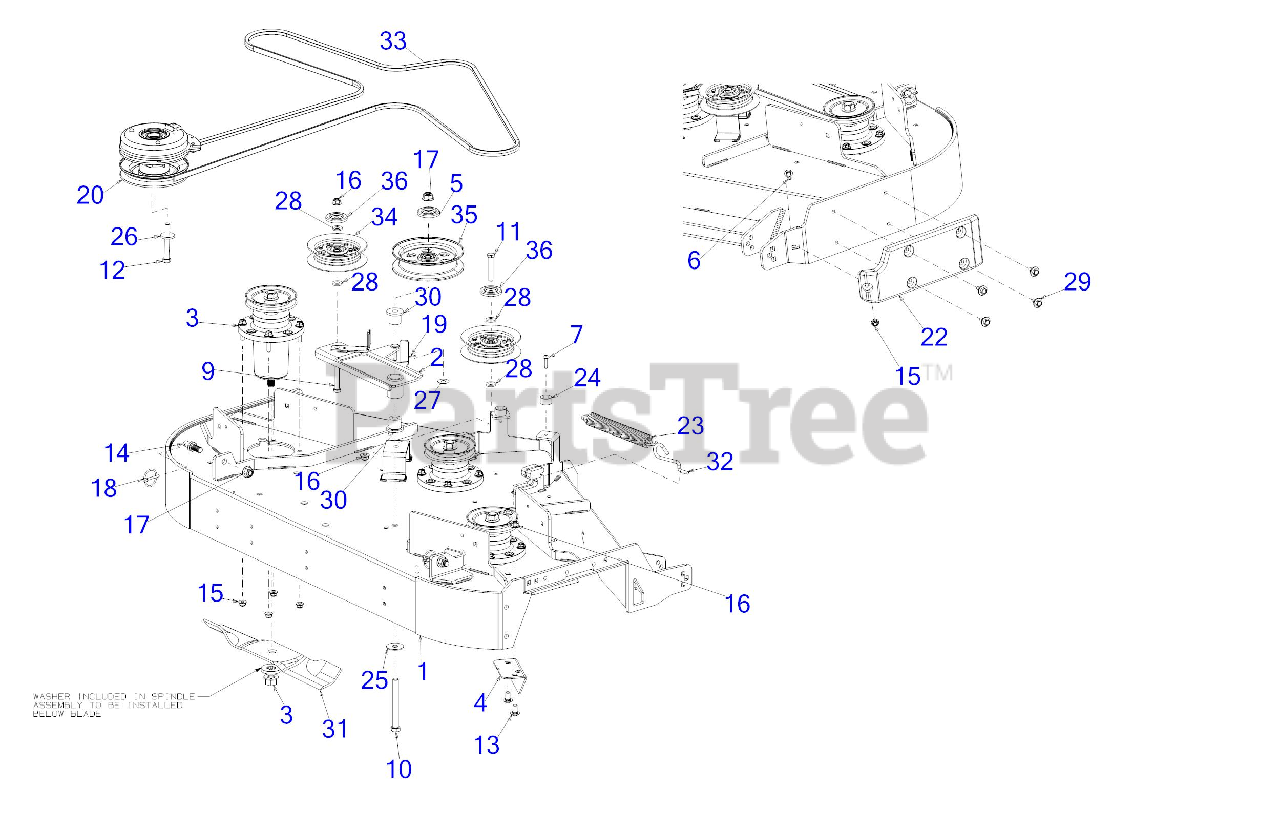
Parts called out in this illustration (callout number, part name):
2	IDLER ARM ASSEMBLY
3	SPINDLE ASSEMBLY
3	Cub Cadet 48" SPINDLE ASSEMBLY (07417)
5	PULLEY CAP
6	CARRIAGE BOLT 5/16-18 x 1.00
7	SCREW 1/4-20 x 1.0
9	HEX SCREW-3/8-16X2.5 GR5
10	SCREW 1/2-13 x 4.5 GR 5
11	SCREW 3/8-16 x 2.25 GR5
12	SCREW 7/16-20 x 3.25 GR5
13	CARRIAGE BOLT 3/8-16 x .75
15	FLANGE LOCK NUT 5/16-18
19	COTTER PIN 3/32
20	ELECTRIC PTO CLUTCH
22	DECK SKID PLATE (LH)
23	EXTENSION SPRING
25	WASHER .51 x 1.5 x .07
26	FLAT WASHER .445 x 1.248 x .170
27	FLAT WASHER
28	FLAT WASHER
29	SHOULDER SCREW .43X.29X5/16-18 TT
30	SHOULDER SPACER
31	17" BLADE (HI LIFT)
31	Cub Cadet 48" HI LIFT BLADE SET
31	17" HI-LIFT BLADE 0.756 ID
31	LOW-LIFT 17" BLADE (48"DECK)
31	BLADE-HI LIFT 17.0
31	17" BLADE (MULCH)
32	DECK SPRING HOOK
33	DECK BELT A SEC x 137"
33	Cub Cadet 48"Z-FORCEDECK BELT (05012)
34	IDLER PULLEY 4.0
35	FLAT IDLER PULLEY 5"
36	IDLER PULLEY CAP
